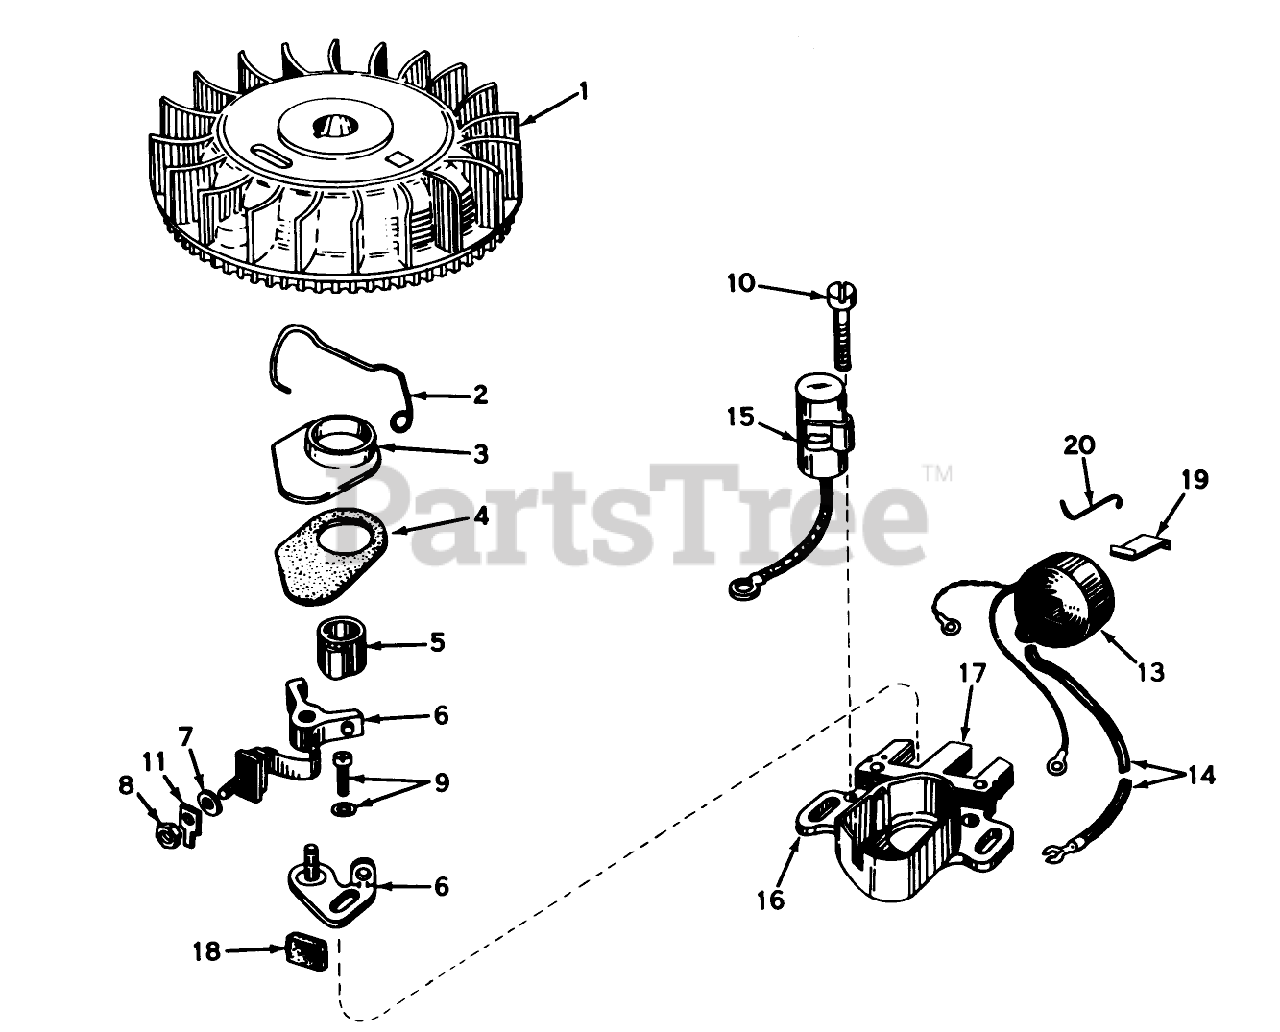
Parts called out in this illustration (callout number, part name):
1	FIywheel
2	Spring Breaker Box
3	Cover, Dust
4	Gasket Dust Cover
5	Cam, Breaker
6	Breaker Assy.
7	Washer
8	DECAL
9	Breaker Screw
10	Condenser Screw
11	Terminal, Ground
13	Coil Assy. (Incl. No. 12)
14	Wire, Lead
15	Condenser
16	Core Plate
17	Stator Assy., (Incl. Nos. 2, 3, 5 thru 14 16 thru 19)
18	Felt,Cam Wiper
19	Spring Coil Wedge
20	Clip, Coil
